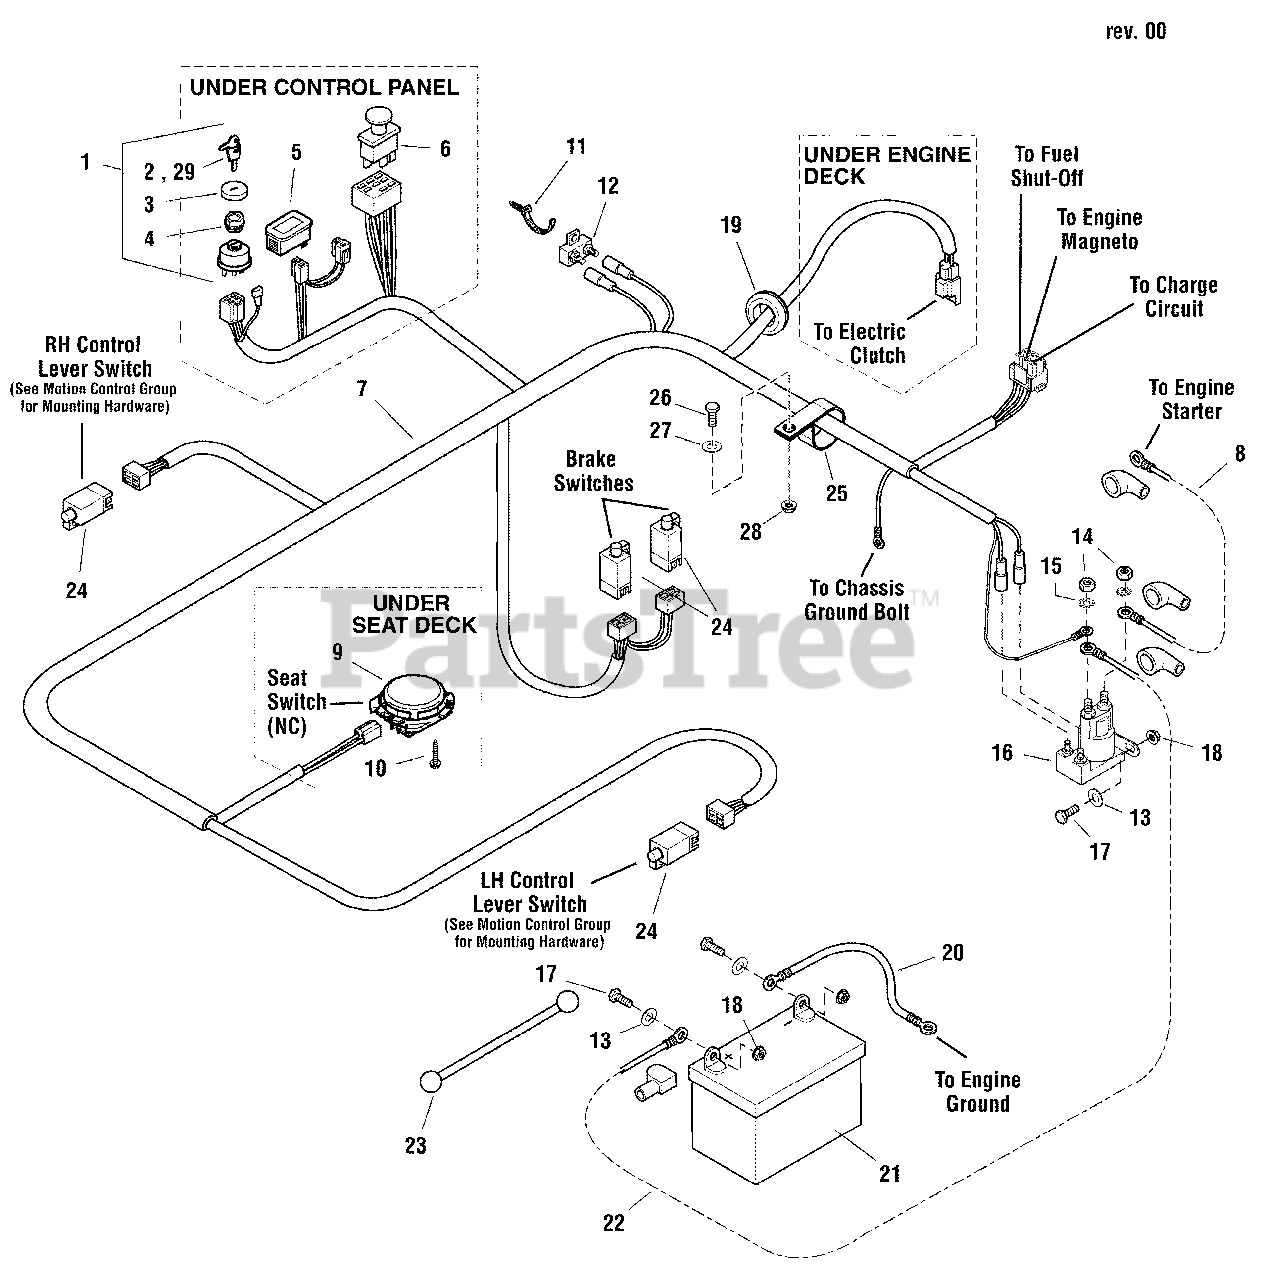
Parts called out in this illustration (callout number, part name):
1	SWITCH ASMY-IGNITION INDAK NO KEYS
2	KEYS. BLISTER PK KIDS+MWRS DON'T MIX, USA Models Only
3	COVER (SV)
4	PLASTIC NUT (SV)
5	HOUR METER, DIGITAL
6	SWITCH, PTO
7	WIRE HARNESS, CONSUMER Z
8	BATTERY CABLE, POSITIVE, 22"
9	SWITCH, SEAT, GRAY, NC (BOLT IN)
9	SWITCH, SEAT, GRAY, NC (TWIST IN)
10	BOLT, HEX WASHER HEAD PLASTITE, 1/4 X 1/2
11	CABLE TIE-PUSH MOUNT
12	CIRCUIT BREAKER, 20A
13	WASHER, 1/4 SAE (5025154)
14	NUT, HEX JAM, 5/16-24 (SV)
15	WASHER, LIGHT LOCK, 5/16 (SV)
16	SOLENOID-4 POLE 12 VOLT DC (TROMBETTA)
17	BOLT, 1/4-20 X 3/4" GD5 YZ
18	NUT, 1/4-20 HEX SERR. FLANGE
19	GROMMET, 3/4
20	BATTERY CABLE, NEGATIVE, 14"
21	BATTERY, WET ( BCIU1, 340 CCA)
22	BATTERY CABLE, POSITIVE, 15"
23	STRAP-BLACK RUBBER
24	SWITCH, PLUNGER, N.O./N.C.
25	CLAMP, VINYL
26	BOLT, 3/8-16 X 1 GD5 YZ
27	WASHER, 3/8 SAE
28	NUT, 3/8-16 HEX, NYLOCK FLANGE
29	KEYS, BLISTER PK KIDS+MWRS DON'T MIX, EXP, CE MODELS ONLY
